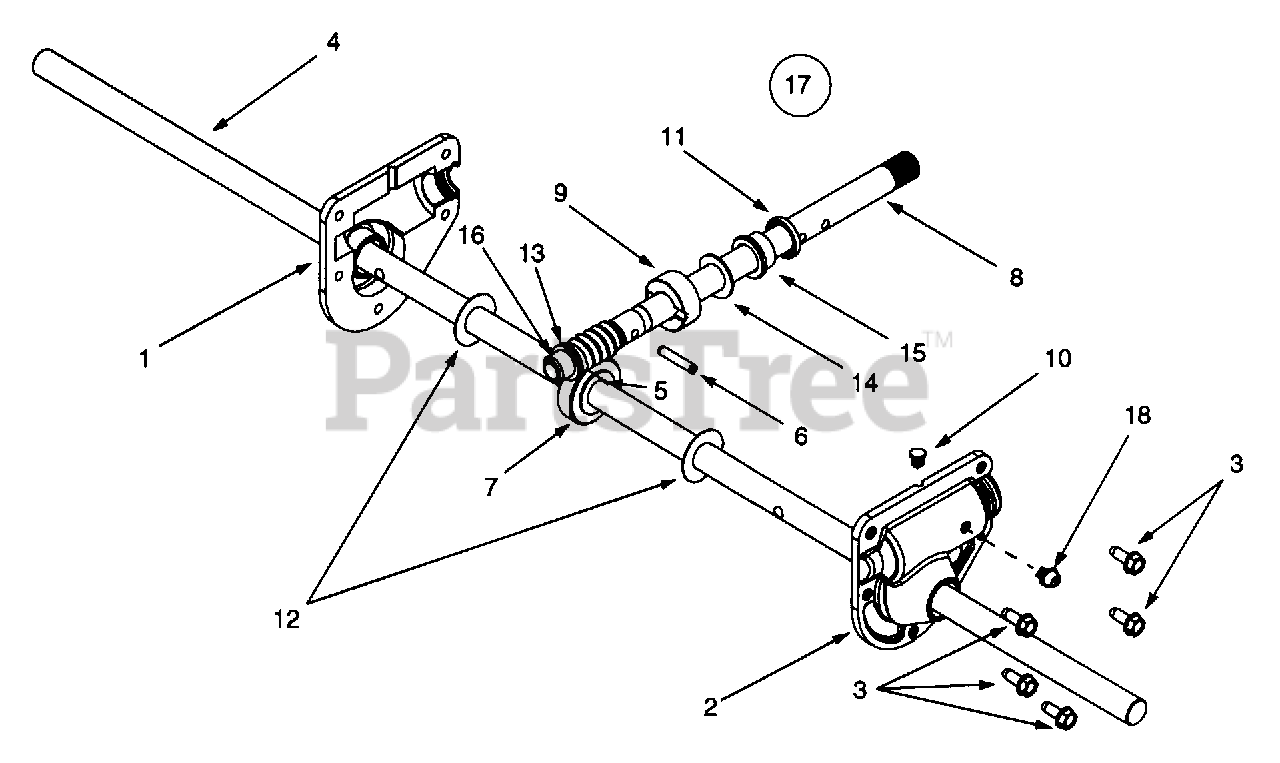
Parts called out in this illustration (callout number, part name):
1	RH Housing
2	LH Housing w/Fitting
3	Self Tapping Screw, 1/4-20 x .75
4	Spiral Axle, 30"
4	Spiral Axle, 26"
5	Hi-Pro Key, 3/16 x 5/8
6	Spring Spiral Pin, .25 x 1.25
7	Worm Gear, 20-tooth
8	Worm Shaft
9	Thrust Collar
10	Grease Plug
11	Grease Seal
12	Flat Washer, .76 x 1.5 x .030
13	Flat Washer, .508 x 1.0 x .020
14	Flat Washer, .76 x 1.5 x .060
15	Flange Bearing, .75 x 1.0 x .59
16	Flange Bearing, .503 ID x .75 OD
17	Gear Assy Complete, 30"
17	Gear Assy Complete, 26"
18	Grease Fitting, 3/16" Drive
18	Grease (Two Ounces)
